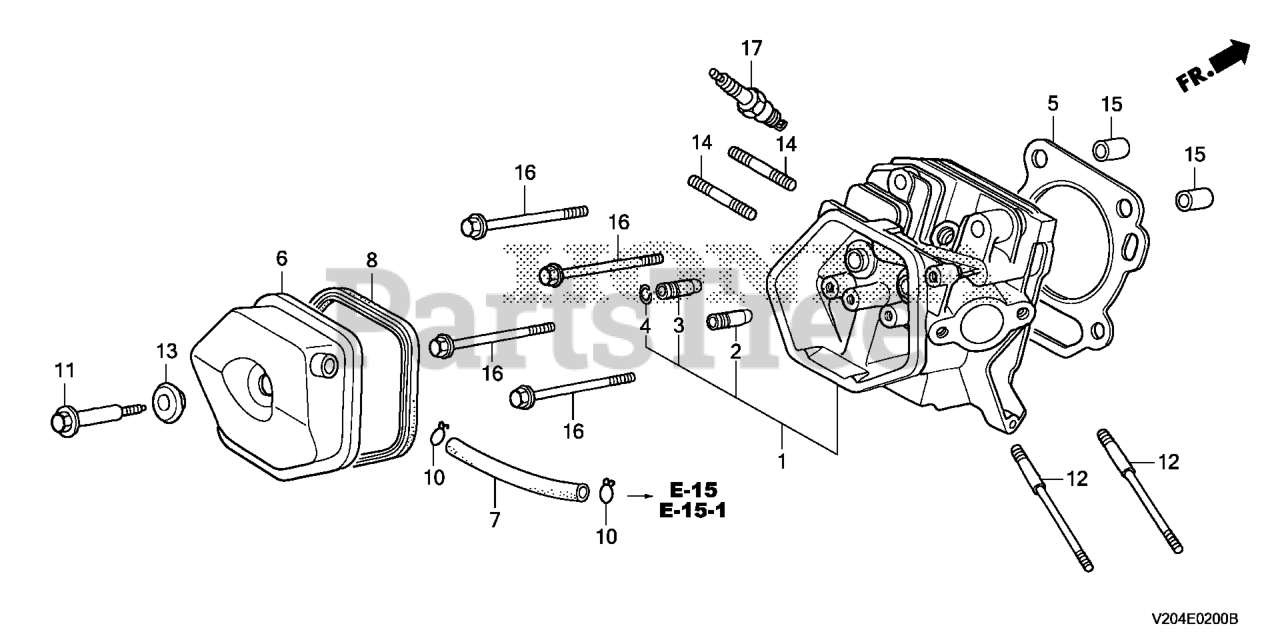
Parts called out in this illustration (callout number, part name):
1	CYLINDER HEAD
2	GUIDE, VALVE (OS)
3	GUIDE, EX. VALVE (OS)
4	CLIP, VALVE GUIDE
5	GASKET, CYLINDER HEAD
6	COVER, HEAD (BREATHER TUBE JOINT)
7	TUBE, BREATHER
8	GASKET, CYLINDER HEAD COVER
10	CLIP, BREATHER TUBE
11	BOLT, HEAD COVER
12	BOLT, STUD (8X123)
13	WASHER, HEAD COVER
14	BOLT 2, STUD (8X32)
15	PIN A, DOWEL (12X20)
16	BOLT, FLANGE (10X80)
17	SPARK PLUG (BPR6ES) (NGK)
17	SPARK PLUG (W20EPR-U) (DENSO)
